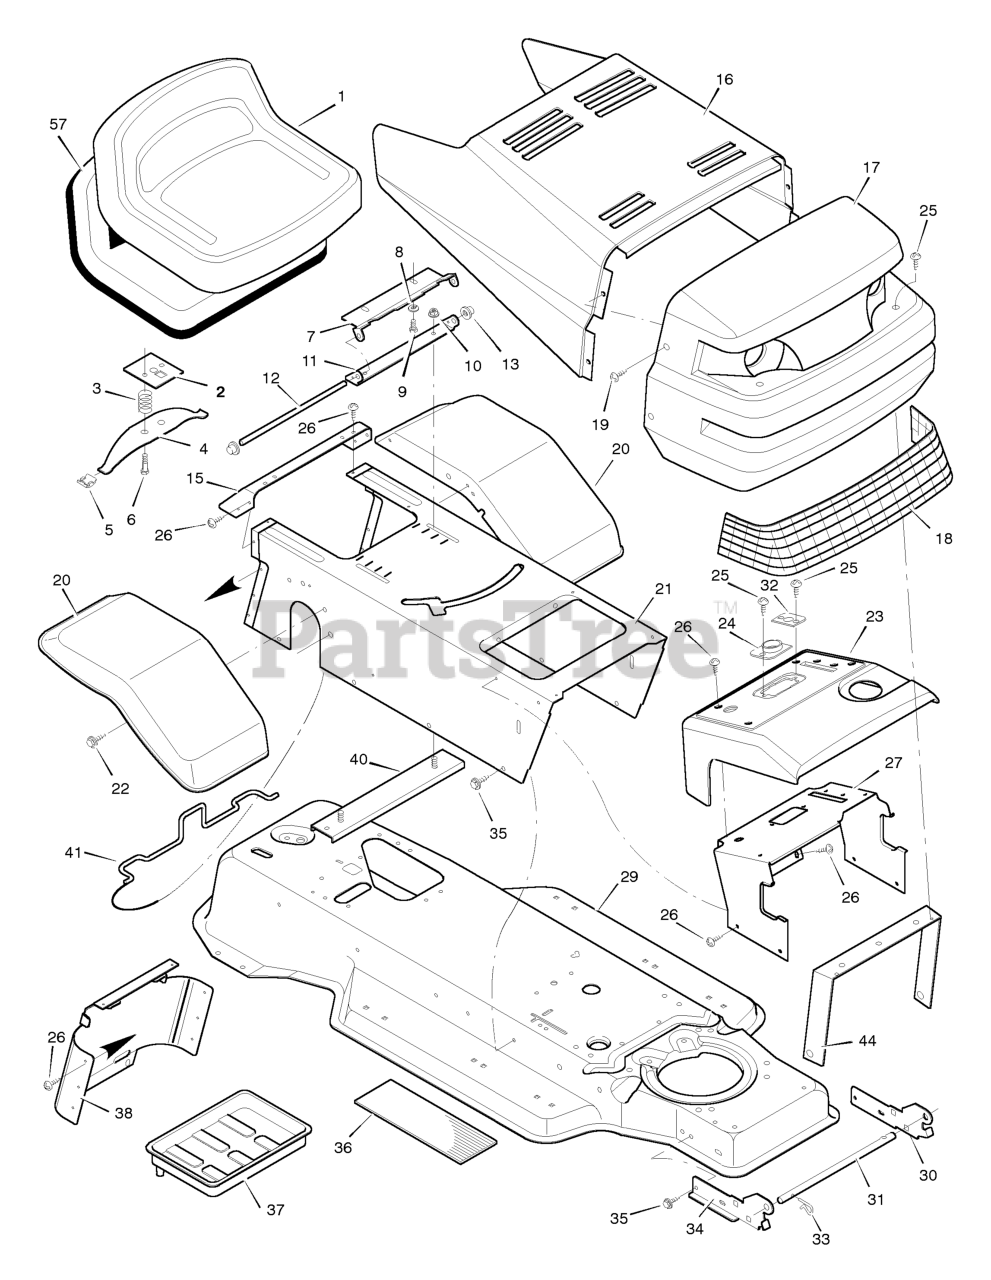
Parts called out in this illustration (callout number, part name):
1	Seat Cover
2	Plate Assembly, Switch
3	Spring, Compression
4	Spring, Seat
5	Glide, Spring
6	Bolt, Shoulder
7	Support, Seat
8	Lockwasher
9	Bolt, Hex
10	Locknut, Flange
11	Bracket, Pivot
12	Rod, Pivot
13	Cap, Push On
15	Fender, Apron
17	Grille Assembly
21	Console Assembly
23	Dash Panel
24	Bearing, Steering
26	Screw
27	Support, Dash
29	Frame Assembly
30	Bracket, Left Grille
31	Rod, Pivot
32	Bearing
33	Pin, Hair
34	Bracket, Right Grille
37	Tray, Battery
38	Cap, Console
39	Bolt
40	Channel Assembly
41	Clamp, Battery
44	Brace, Grille
57	Pan, Seat (with foam)
